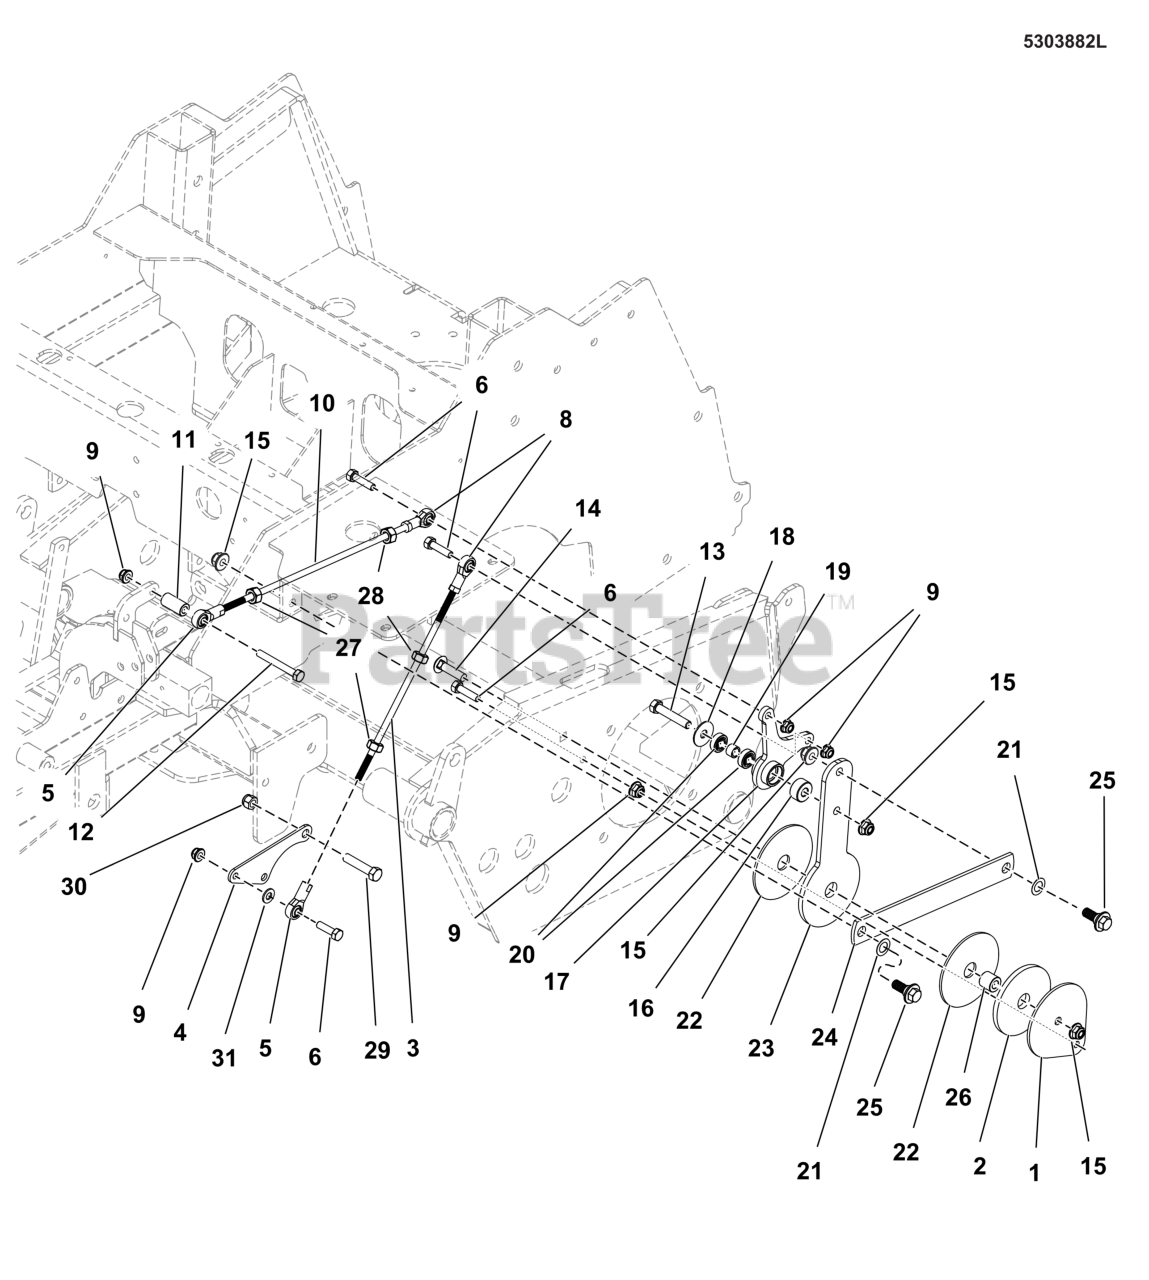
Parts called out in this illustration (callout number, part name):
1	PLATE, CTRL SYSTEM LK
2	PAD, .77 X 3.50 X .25
3	ROD, HYDRO LINKAGE
4	PLATE, CONTROL MOUNT
5	BALL JOINT 5/16-24 RH
6	BOLT, 5/16-18 X 1-1/4
8	BALL JOINT 5/16-24 LH
9	NUT
10	ROD, HYDRO LINKAGE
11	SPACER, .33X.63X1.25
12	BOLT
14	BOLT, 3/8-16 X 1-1/2
15	NUT, 3/8-16 HEX NYLOCK
17	PIVOT, CONTROL SYSTEM
18	WASHER, 3/8" FENDER
19	SPACER, .39X.55X.38
20	BEARING, .375ID
21	WAVE WASHER
22	PAD, CONTROL SYSTEM
23	PLATE, CTRL SYST ARM
24	LINK, Control
25	BOLT, Washer
26	SPACER, .39X.75X.69
28	NUT, 5/16-24 HEX, LH
29	BOLT, 7/16-14
30	NUT, 7/16-14 HEX
31	WASHER
